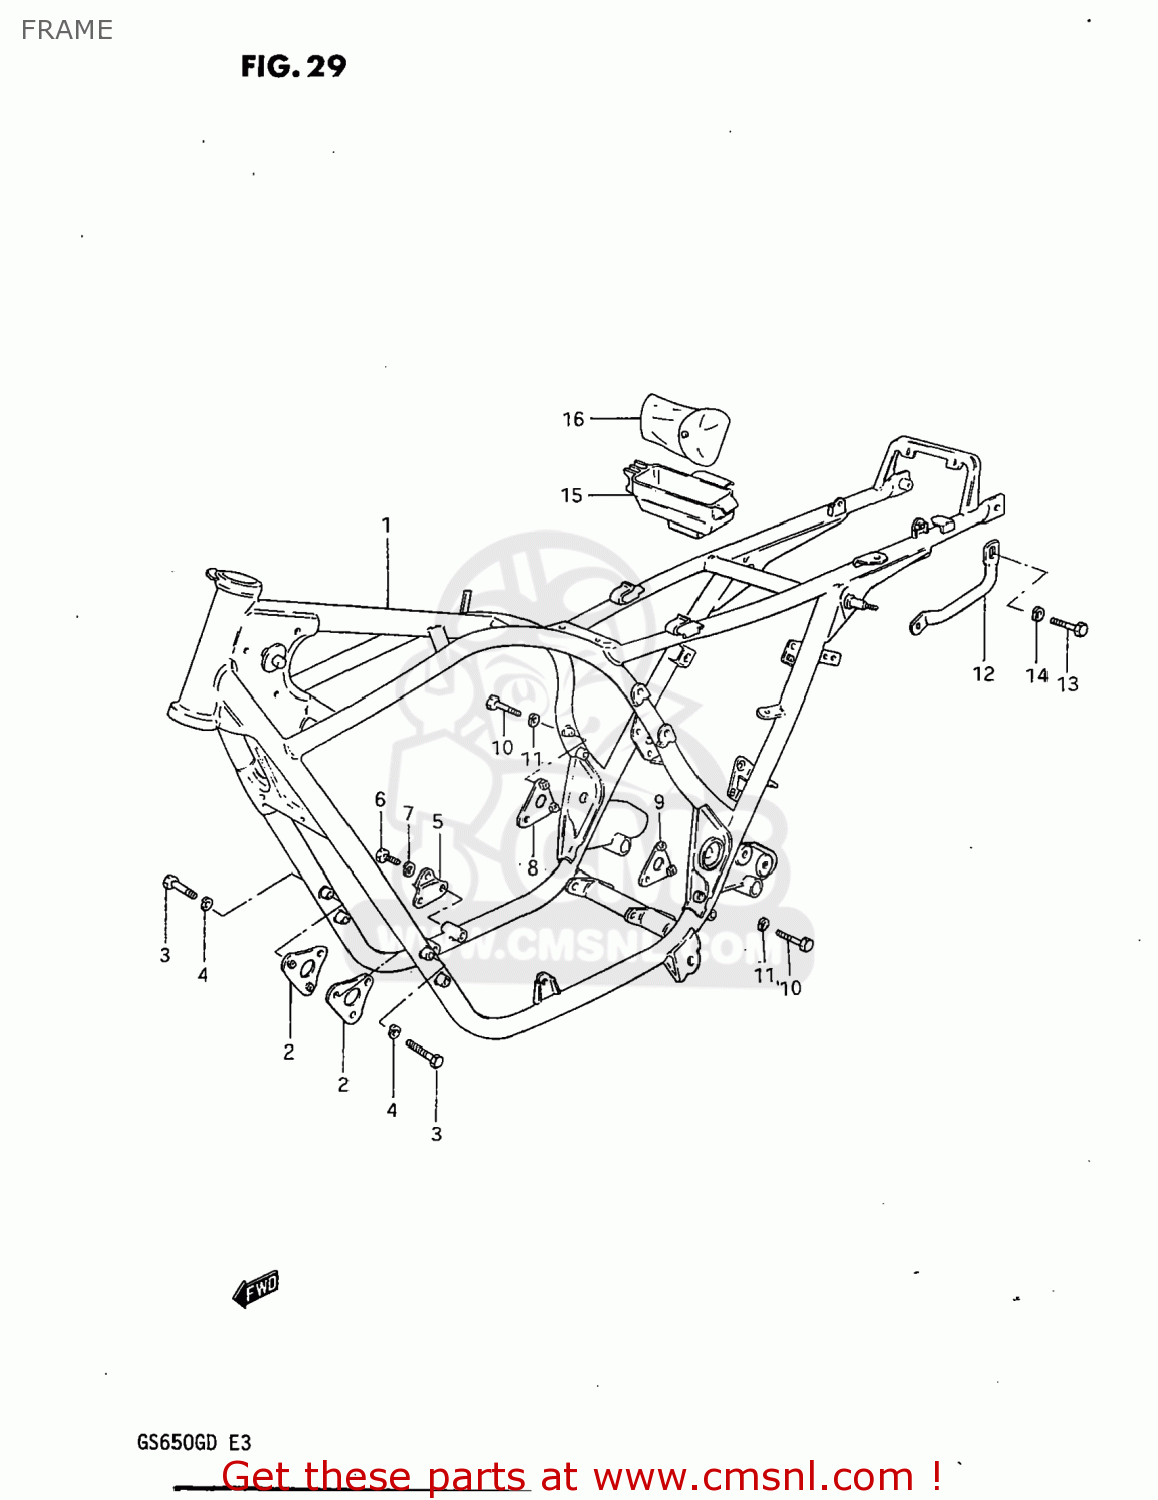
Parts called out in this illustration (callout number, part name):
1	FRAME
2	PLATE,ENGINE MOUNTING NO
3	BOLT
4	LOCK WASHER
5	BOLT,CRANKCASE ADJUST
6	BOLT
7	LOCK WASHER
8	PLATE,ENGINE MOUNTING NO
9	PLATE,ENGINE MOUNTING
10	BOLT
11	LOCK WASHER
12	GRIP,FRAME HANDLE
13	BOLT
14	WASHER
15	HOLDER,TOOL
16	TOOL SET
